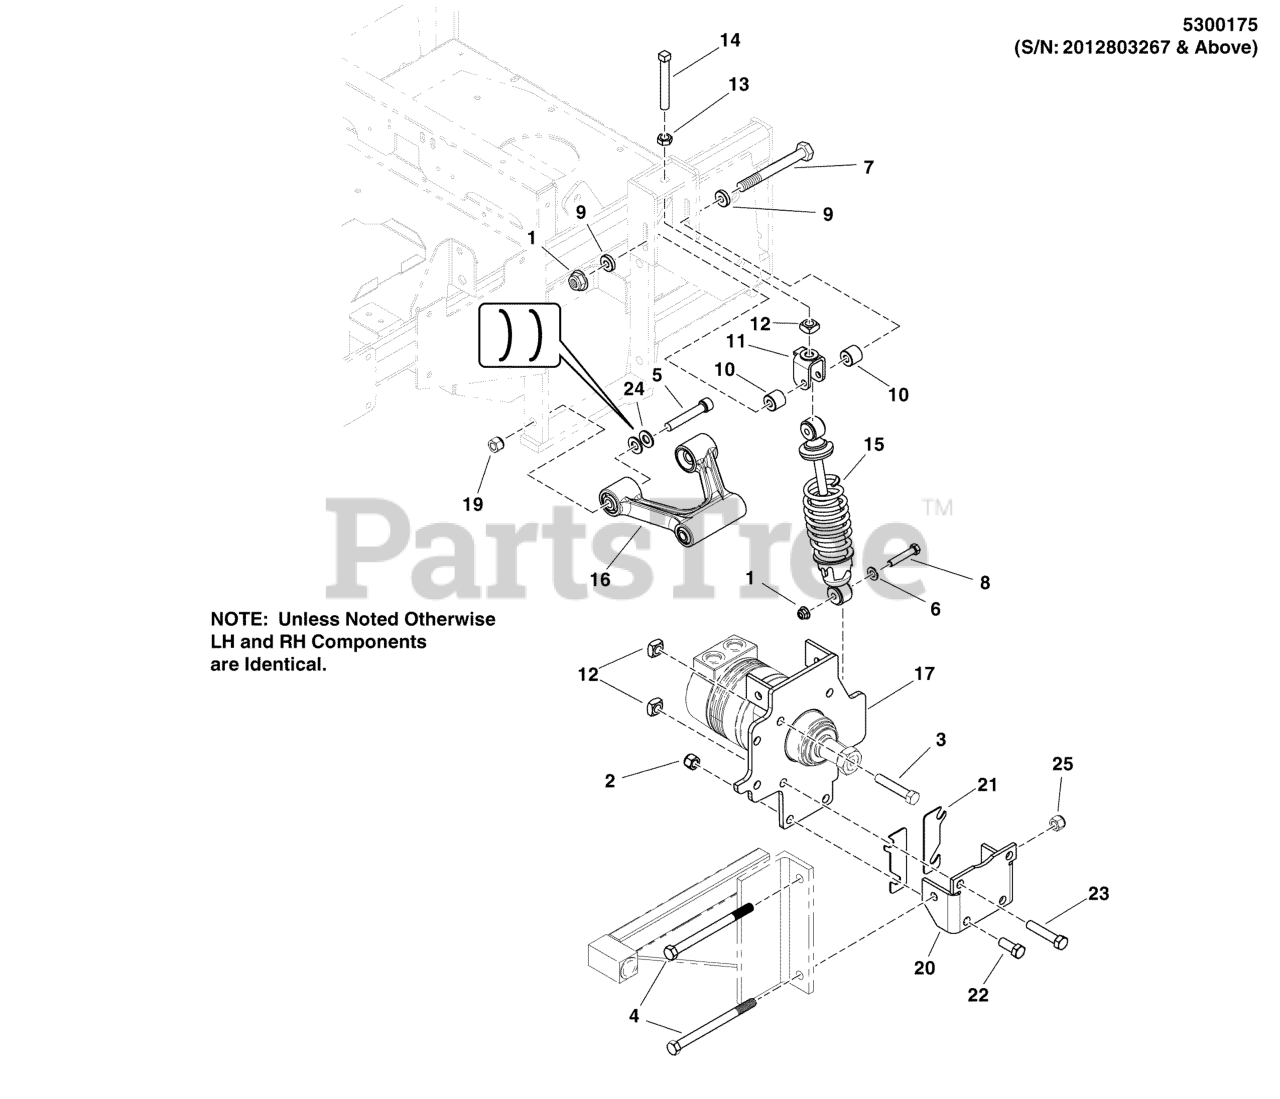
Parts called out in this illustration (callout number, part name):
1	NUT, 3/8 - 16 HEX NYLOCK FLANGE
2	NUT, Hex, Nylon Lock, 1/2-20
3	BOLT, 1/2-13 X 2-3/4 GD5 CZ
4	BOLT, 1/2-13 X 6-1/2" GD8 YZ
5	BOLT, 1/2-13 X 3-1/4" ALLEN HEAD
6	WASHER, 3/8 SAE
7	BOLT, 3/8-16 X 5" GD5
8	BOLT, 3/8-16 X 2, GD5, CZ
9	SPACER, .39 X 1.00 X .25
10	SPACER, .39 X 1.00 X .88, CZ
11	WELD, JACK BOLT PLATFORM - RED
12	NUT, 1/2-13 Square
13	NUT, Hex, Jam, 1/2-13
14	SET SCREW, Square Head, 1/2-13 x 3
15	SHOCK/SPRING ASSEMBLY, IS3000
16	ASSM, A-ARM WITH BEARINGS
17	WELD, MOTOR MOUNT, LH - 3100 - BLK
19	NUT, 1/2-13 HEX NYLOCK FLANGE GR8, YZ
21	SHIM, CAMBER - PLATED
22	BOLT, 1/2-20 X 1-3/4" GD8 CZ
23	BOLT, 1/2-13 X 3" GD5 CZ
24	BELLEVILLE WASHER, 1.259 X .512 X .138 YZ
25	NUT, Hex Flange, Nylock, 1/2-13
